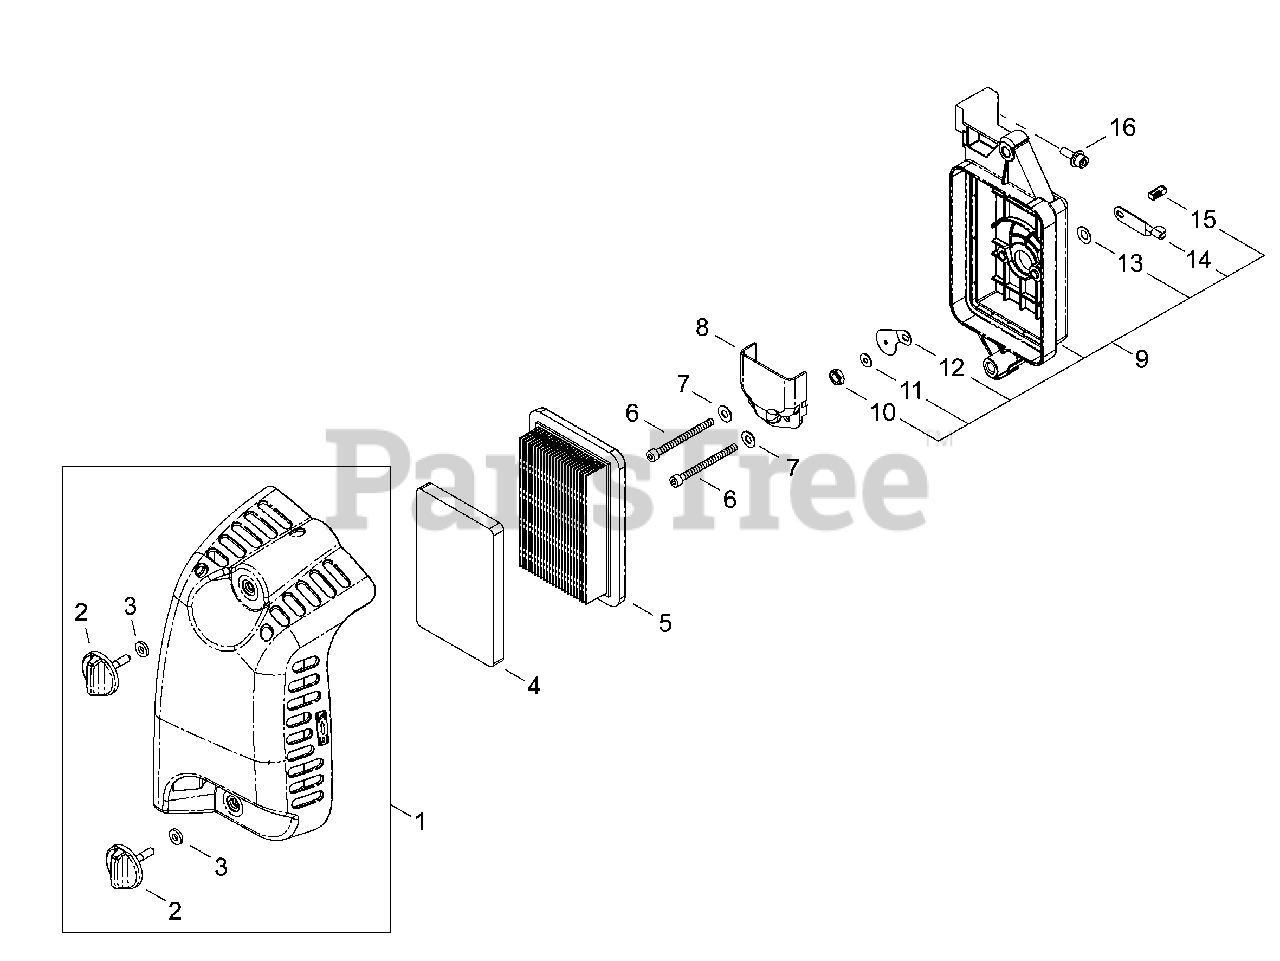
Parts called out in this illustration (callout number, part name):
1	COVER ASSY, AIR FILTER
2	THUMBSCREW
3	WASHER 5
4	PRE-FILTER, FOAM
5	FILTER, AIR
6	BOLT SS M5×70
7	WASHER 5.3×10×1
8	PLATE, DEFLECTOR
9	CASE ASSY, AIR FILTER
10	U-NUT M6
11	WASHER, SPRING 6
12	PLATE, CHOKE
13	WASHER, CONE M6
14	LEVER, CHOKE
15	SHAFT, CHOKE
16	BOLT M5×20
